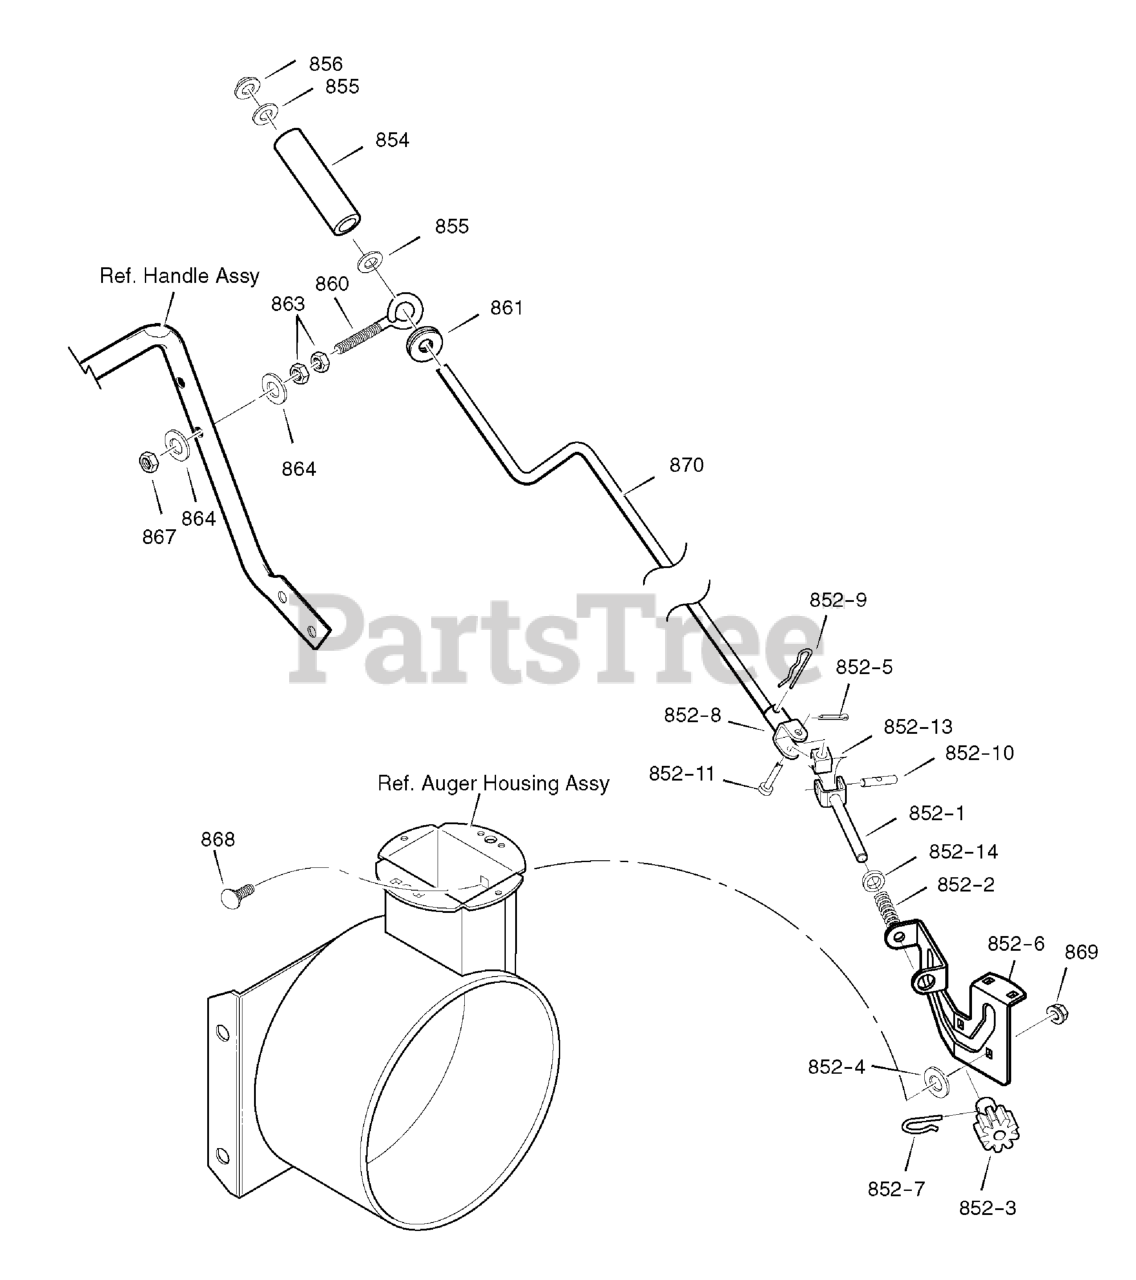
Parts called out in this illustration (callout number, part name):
852-1	ASSEMBLY, Yoke & Rod
852-2	SPRING, Compression
852-3	GEAR, Chute Rotation
852-4	WASHER
852-5	PIN, Cotter
852-6	BRACKET, Gear
852-7	PIN, Hair
852-8	ASSEMBLY, Yoke Adapter
852-9	PIN, Hair
852-10	PIN, Universal Joint
852-11	PIN, Clevis
852-13	HOUSING, Universal
854	KNOB, Sleeve
855	WASHER, Flat
856	NUT, Push-Pal, 3/8
860	EYE BOLT, 3/8 - 16 x 6
861	GROMMET, Eye Bolt
863	NUT, Hex Jam, 3/8 - 16
864	WASHER, Flat
867	NUT, Hex Nylock, 3/8 - 16
868	BOLT, Cariage 1/4 - 20 x 1
869	NUT
870	CRANK ASSEMBLY, Chute
